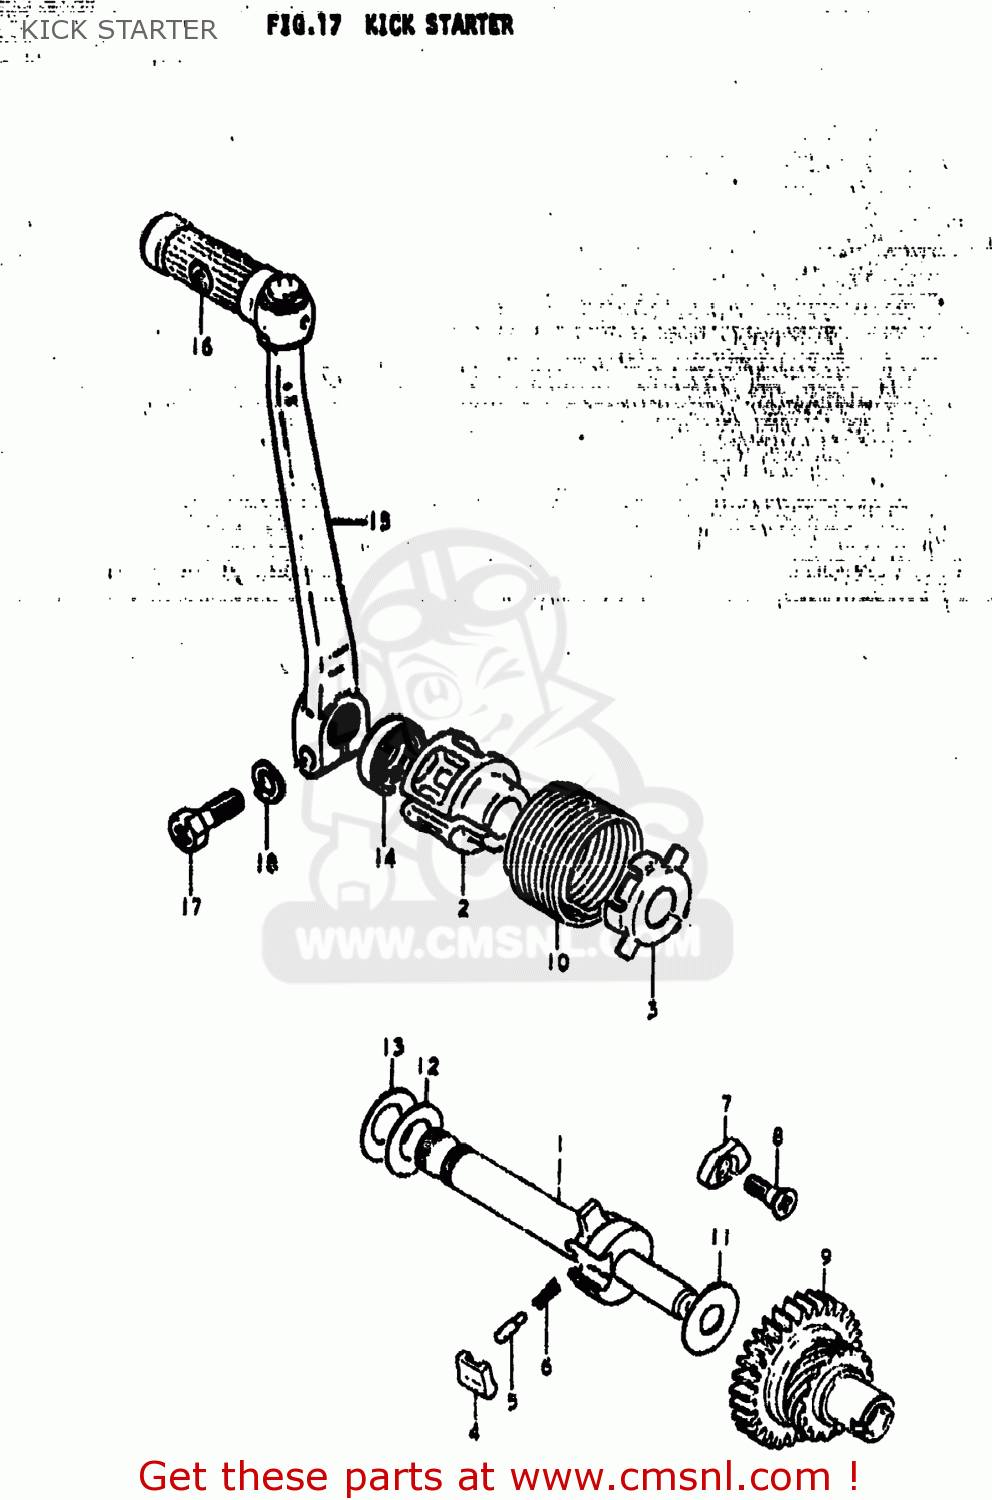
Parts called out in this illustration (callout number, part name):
1	SHAFT,KICK STARTER
2	GUIDE,KICK SHAFT SPRING
3	HOLDER,KICK SHAFT SPRING
4	PAWL,KICK STARTER
5	PIN(5X15.5)
6	SPRING
7	LIFTER,KICK STARTER PAWL
8	SCREW(6X14)
9	GEAR,KICK STARTER DRIVE
10	SPRING
11	WASHER
12	WASHER(16X30X0.5)
13	WASHER
14	SEAL,OIL(16X30X8)
15	LEVER ASSEMBLY,KICK STARTER
16	RUBBER,KICK STARTER PEDAL
17	BOLT
18	LOCK WASHER
